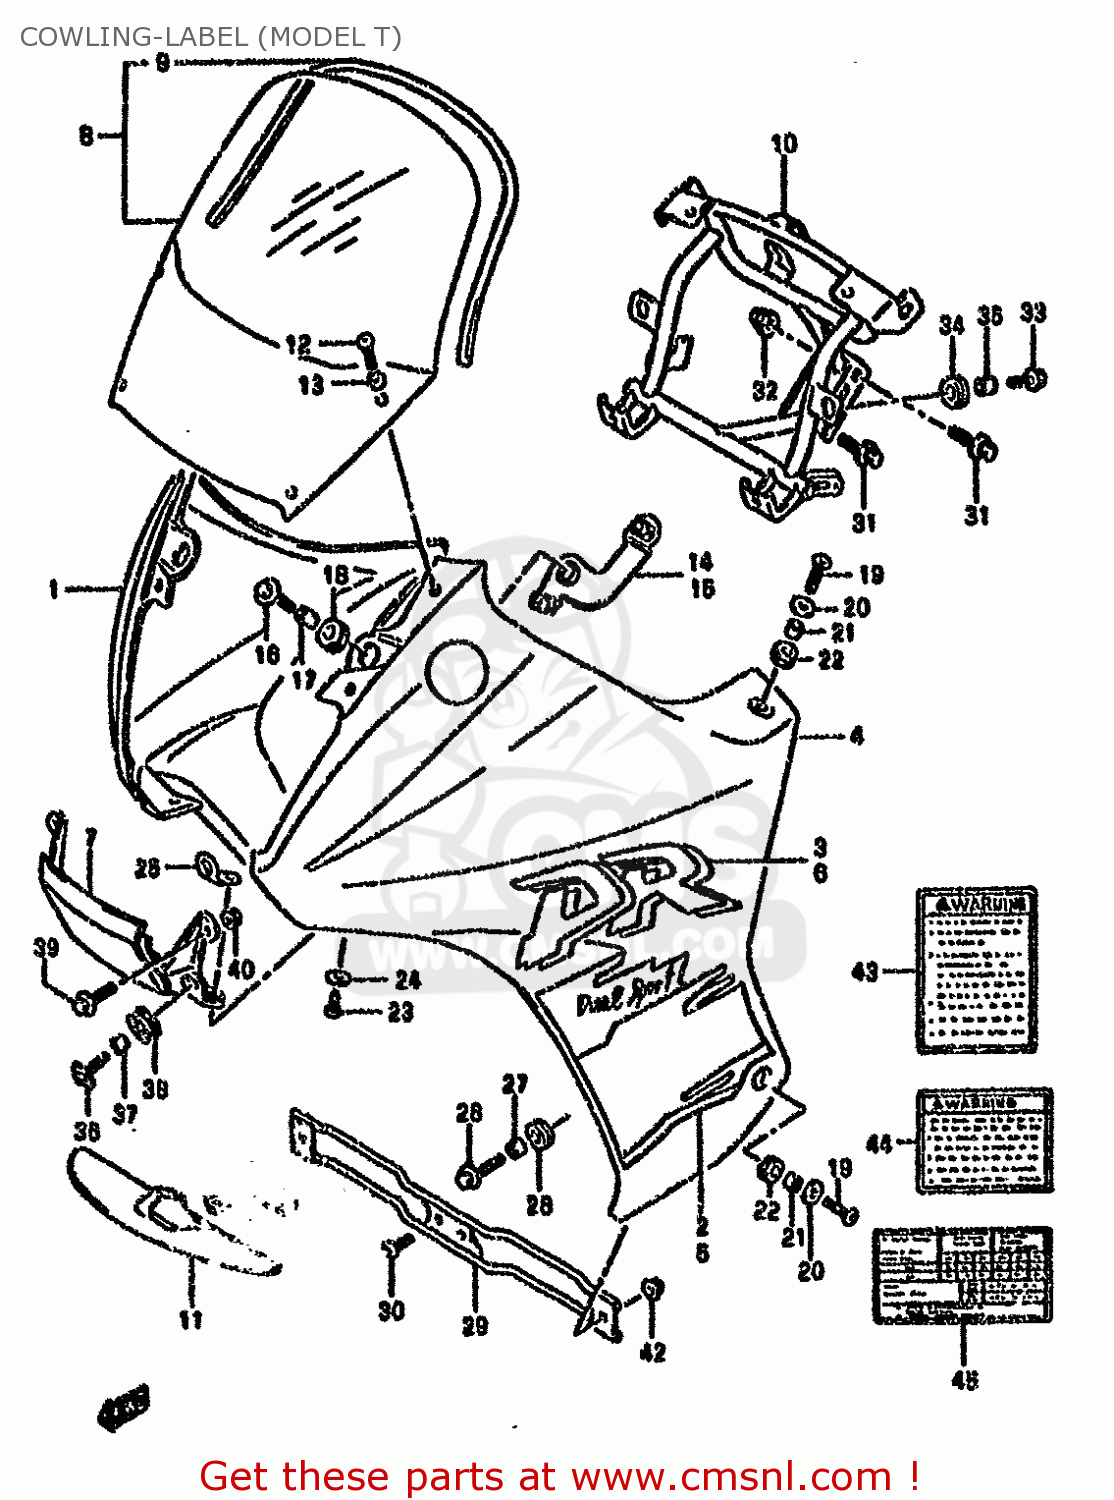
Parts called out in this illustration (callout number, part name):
1	COVER,COWL SIDE RH (GREEN)
2	TAPE,COWL SIDE,R
3	EMBLEM,COWLING SIDE
4	COVER ASSY,COWL SIDE,L
5	TAPE,COWL SIDE,L
6	EMBLEM,COWLING SIDE
7	COVER,COWLING CTR
8	WINDSCREEN
9	MOLDING WINDSCREEN
10	BRACE,COWLING
11	COVER,COWLING FR LWR
12	SCREW
13	WASHER(5.2X11X1)
14	BRACE,SCREEN,R
15	BRACE,SCREEN,L
16	SCREW
17	SPACER (6,8X10X9.4)
18	CUSHION
19	SCREW(6X20)
20	WASHER(6.5X18X1)
21	SPACER (6.1X9X10)
22	CUSHION
23	SCREW (6X18)
24	WASHER(6.5X18X1.5)
25	BRACKET,COWLING FR LWR
26	SCREW(6X25)
27	SPACER (6.1X9X10)
28	CUSHION
29	BRACKET,COWLING LWR
30	SCREW 6X12
31	BOLT
32	NUT
33	BOLT(6X20)
34	CUSHION
35	SPACER (6.1X9X10)
36	SCREW
37	SPACER (6,8X10X9.4)
38	CUSHION
39	SCREW,HEADLAMP (5X20)
40	NUT
41	WASHER
42	NUT
43	LABEL (WARNING SCREEN)
44	LABEL,WARNING
45	LABEL,CAUTION
46	MANUAL,OWNER'S
47	O.M. DR650RSE
48	O.M. DR650RSE
